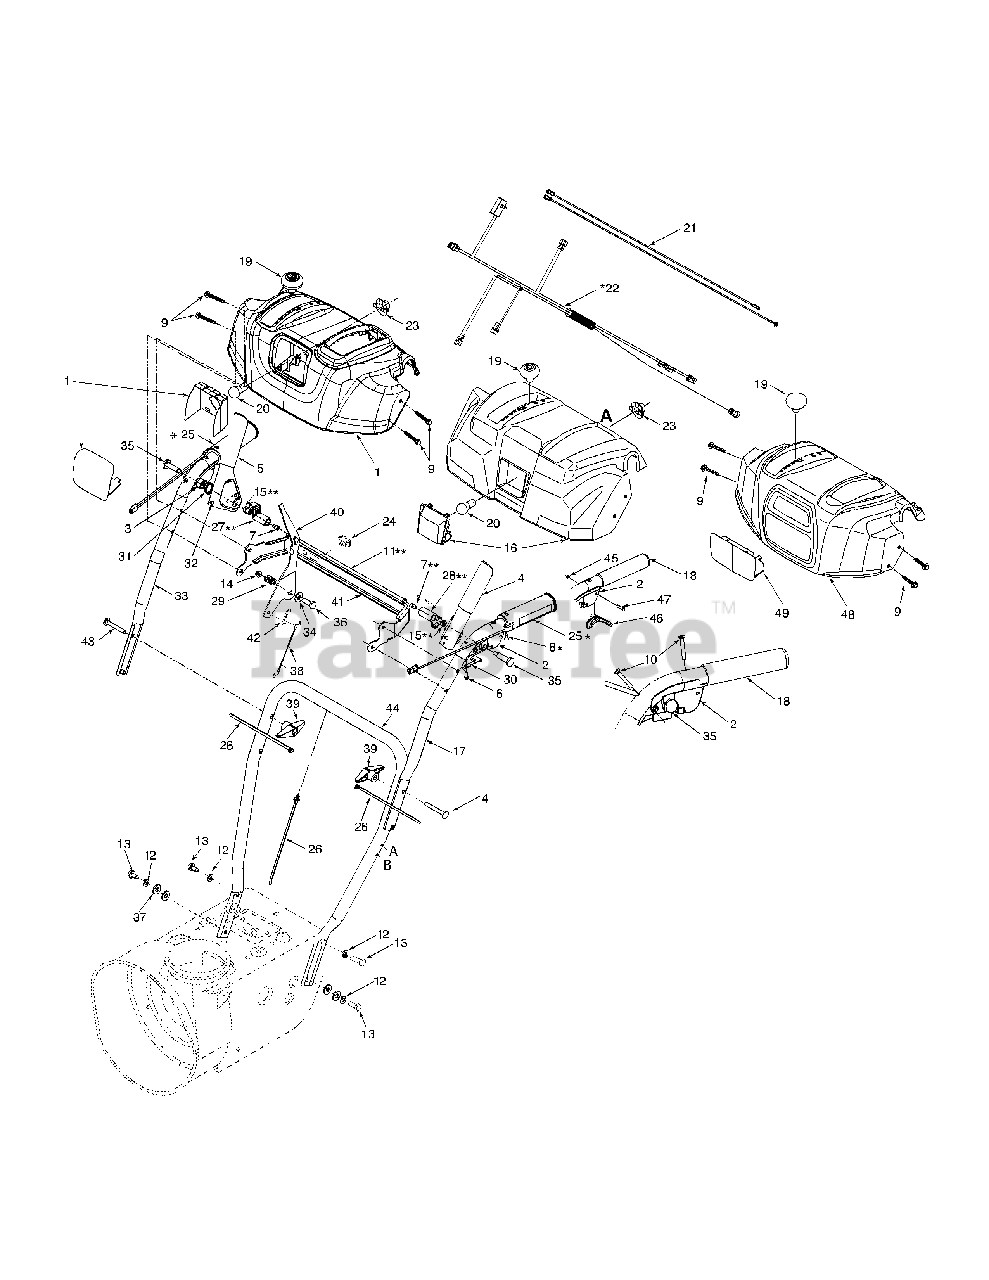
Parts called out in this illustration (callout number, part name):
1	Handle Panel Ass’y - Yellow
2	LH Clutch Lock Handle Ass’y
3	RH Clutch Lock Handle Ass’y
4	Engagement Handle Assembly LH - Black
5	Engagement Handle Assembly RH - Black
6	Screw #8-16 x .50
7	Hex Cap Socket Screw 1/4-20 x .5
8	Oval HD C-Sunk Screw #10 x 5/8
9	Hex TT-Tap Screw 1/4-20 x 1.625
10	Oval C-Sunk Hd Screw 10-24 x 1.375
12	Lockwasher 5/16 ID
13	Hex TT Screw 5/16-18 x .75 Gr. 5 Patch
14	Hex L-Flanged Nut 1/4-20 Gr. F Nylon
15	Hex Shoulder Nut 1/4-20
15	Hex L-Flg Nut 1/4-20 Gr. F Nylon
16	Handle Panel Ass’y - Troy-Bilt
19	Shift Knob - Yellow
20	Lamp #1295 (models with heated grips)
20	Lamp (models w/o heated grips)
21	Wire Harness
22	Heated Grip Wire Harness
23	Socket
25	Heated Grip
26	Cable Tie (w/plug)
26	Cable Tie (w/heated grips)
27	Lock Plate
28	Clutch Lock Cam
29	Compression Spring .38 ID x .88 Lg
30	Spring: Clutch Lock
31	Torsion Spring .8156 x .3038
32	Rubber Bumper
34	Flat Washer .38 ID x .87 OD x .09
35	Shoulder Screw .437 x 1.345: 1/4-20
36	Shoulder Screw .374 Dia. x 1.05 Lg.
37	Flat Washer .344 ID x .688 OD x .065
38	Selector Speed Cable
39	Handle Knob Assembly
41	Panel Support
42	Cotter Pin
43	Carriage Bolt 5/16-18 x 2.25
46	Steering Control - Black
46	Steering Control - Yellow
48	Handle Panel Ass’y - Red (w/lens)
